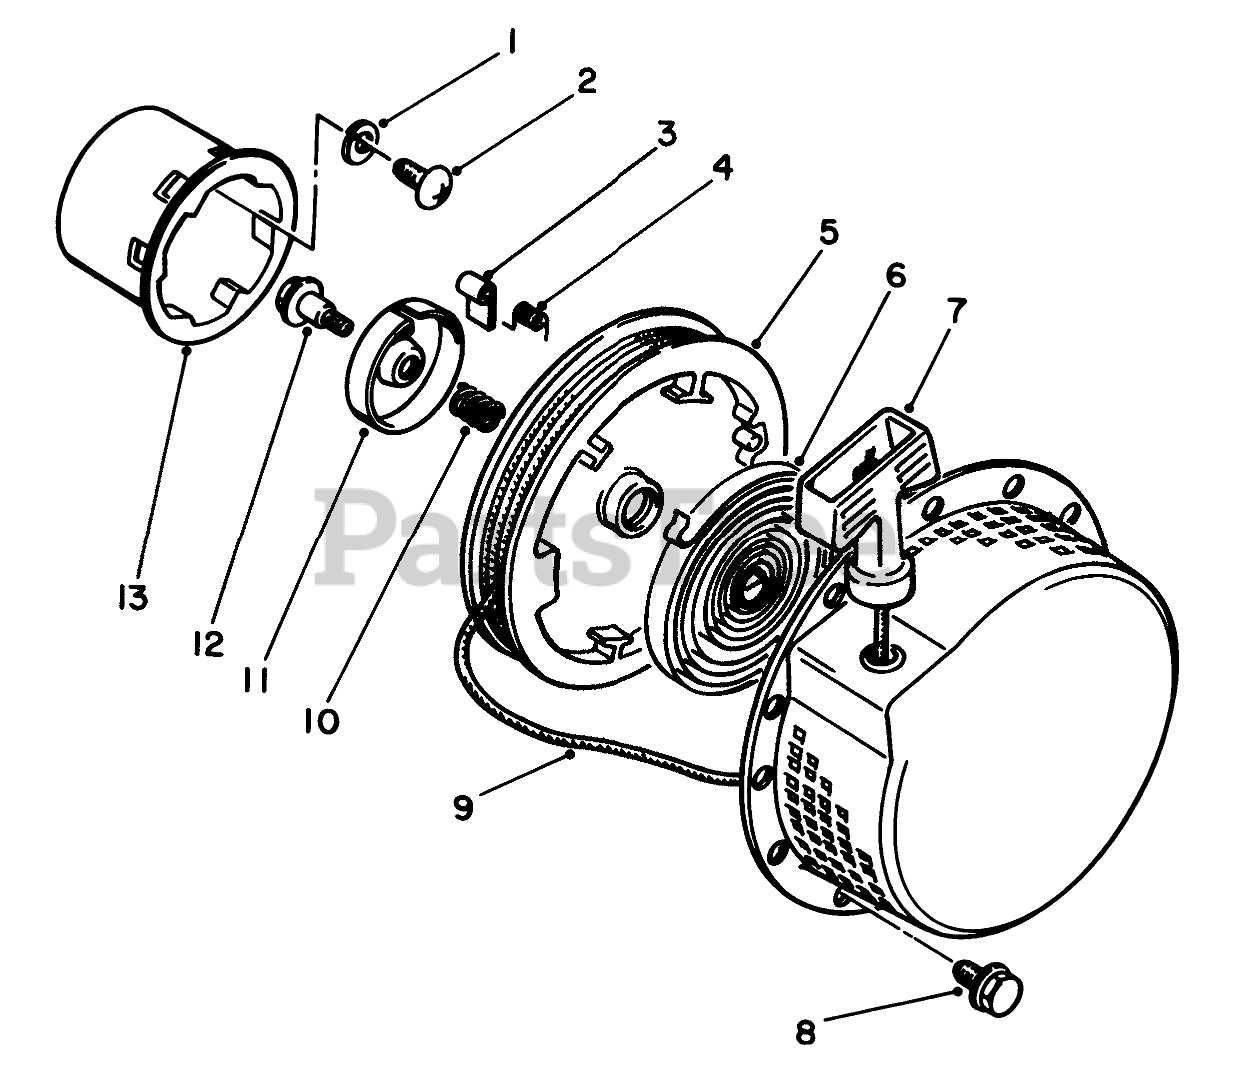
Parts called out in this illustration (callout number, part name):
1	Washer-Lock
2	Screw
4	SPRING
6	SPRING
7	Grip-Hand
9	Starter Rope Assembly (Incl. Ref. #7)
10	SPRING
11	RETAINER
13	Pulley
